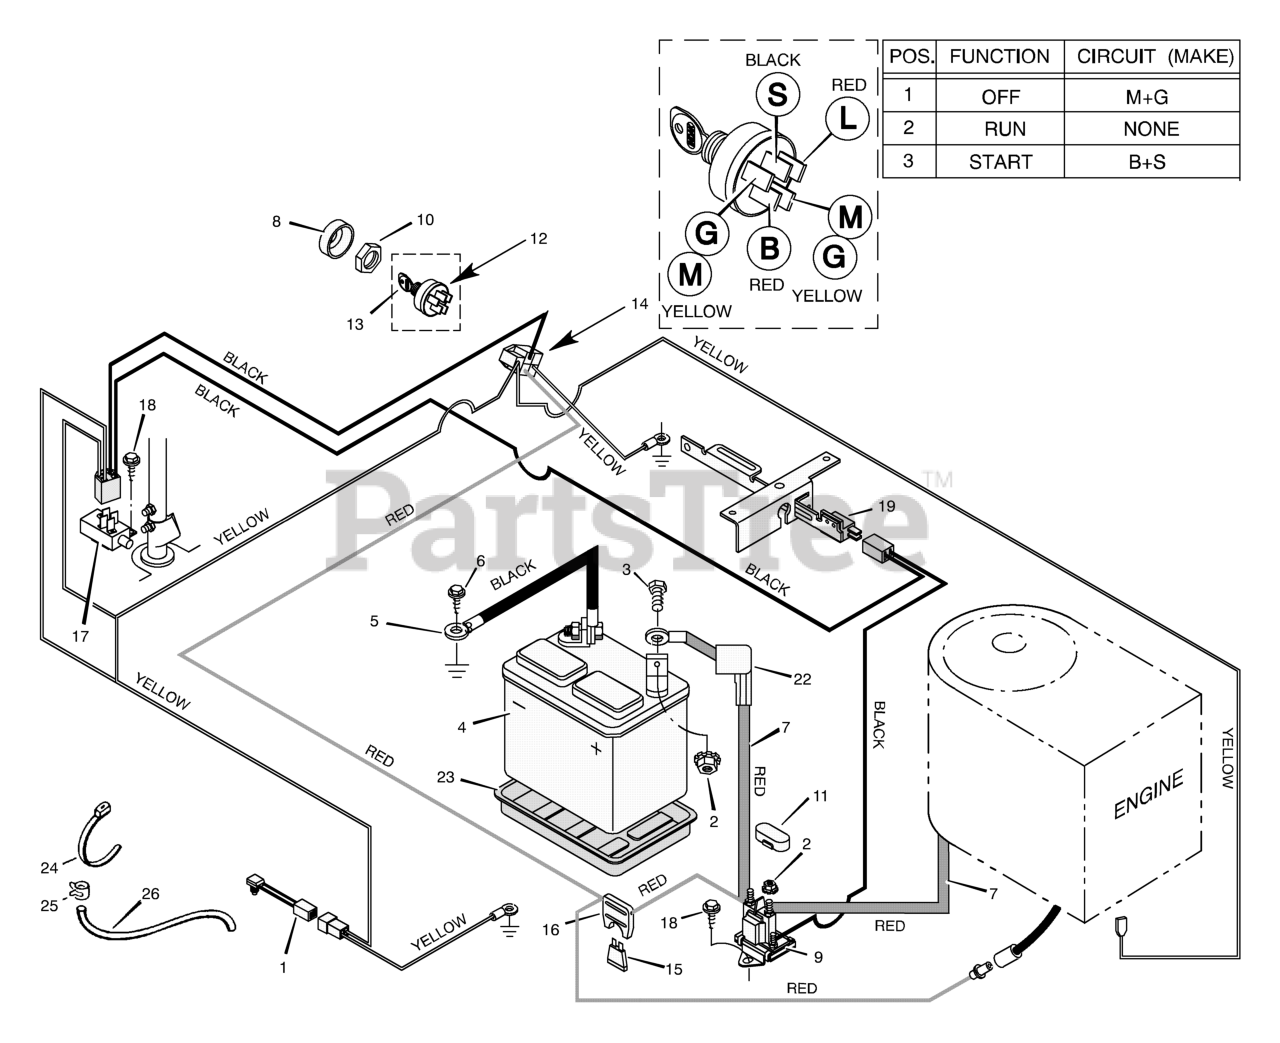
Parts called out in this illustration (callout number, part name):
1	Switch, Seat Sensor
2	Locknut
4	Battery
5	Cable, Battery Ground
7	Cable, Red Battery
8	Cap, Ignition
9	Solenoid
10	Nut, Hex
11	Cover, Solenoid
12	Switch, Ignition
13	Key, Ignition
14	Harness, Chassis Wire
16	Holder, Fuse
17	Switch, Limit
19	Switch, Limit
22	Cover, Terminal
23	Tray, Battery
24	Strap, Tie
26	Drain, Tube
